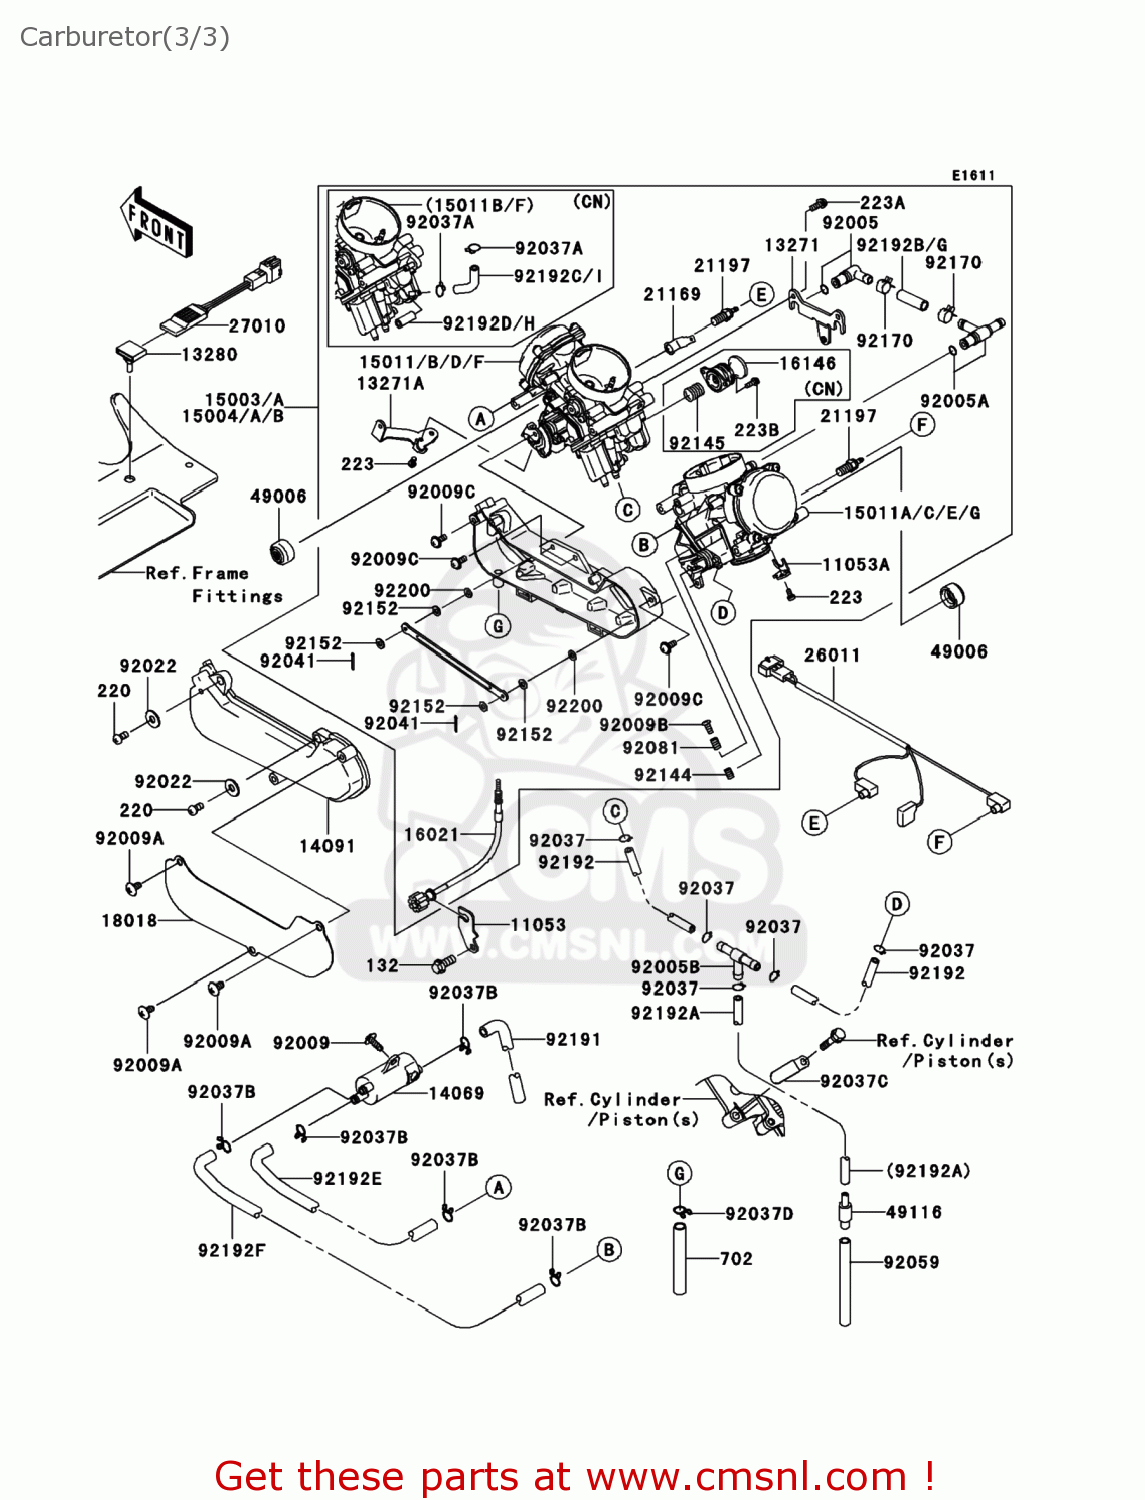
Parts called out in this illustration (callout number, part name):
223	SCREW-PAN-WS-CROS,4X8
223A	SCREW-PAN-WS-CROS,5X1
223B	SCREW-PAN-WS-CROS
702	TUBE-RUBBER
